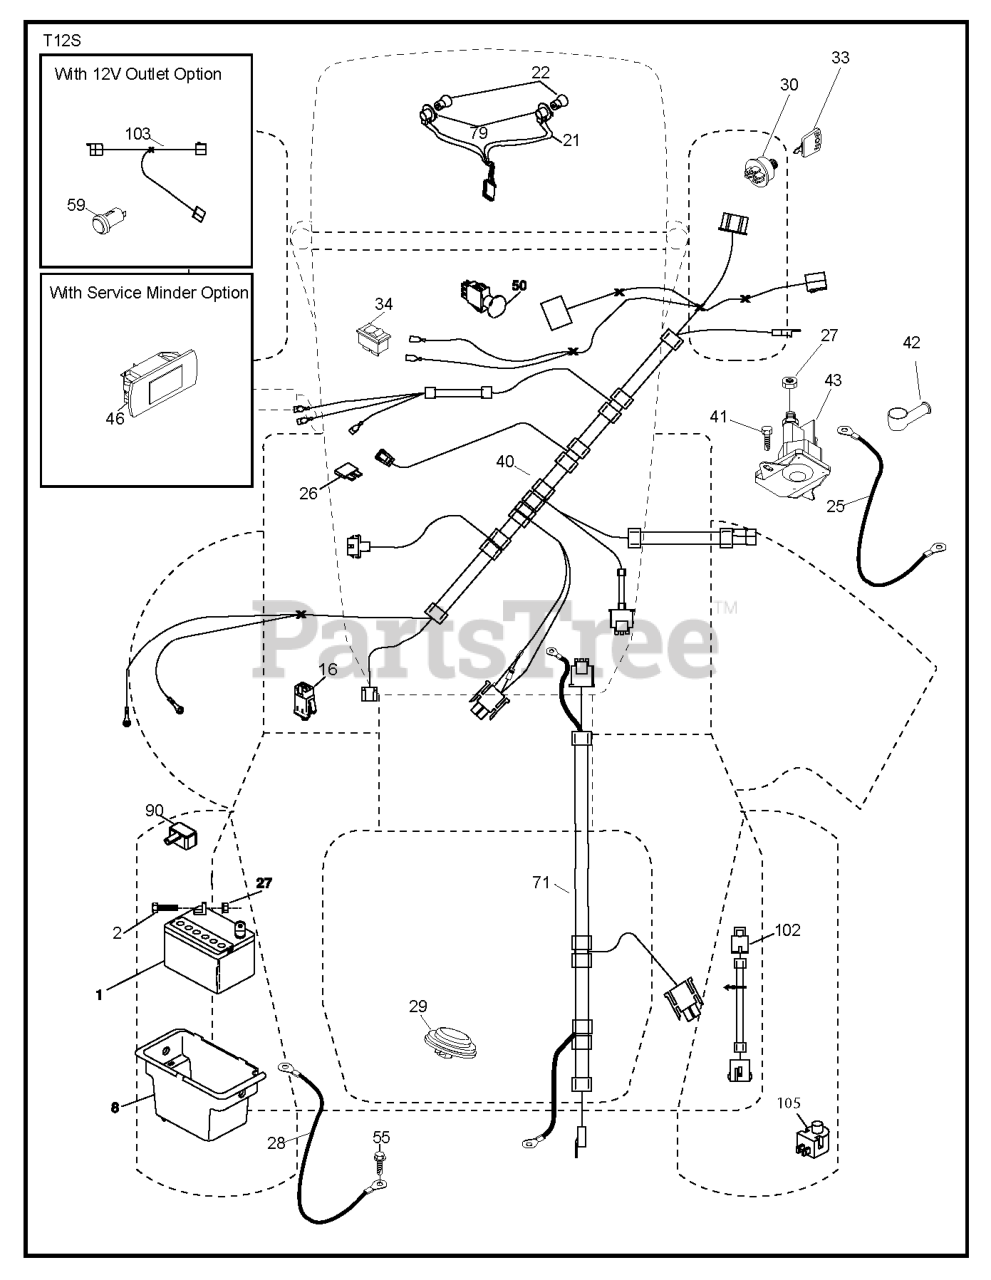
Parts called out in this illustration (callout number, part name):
1	Battery 12 Volt 25 Amp
2	BOLT.HEX.1/4.X.3/4.DICHROMATE
8	BOX.BATTERY.MNT.REAR.L
16	SWITCH INTERLOOK PUSH-IN
21	HARNESS.LIGHT W/4152J BULBS
25	CABLE.STARTER.6GA.BL/RED.14.
26	FUSE 20AMP
27	NUT
28	CABLE.BLACK.18"REAR.BA
29	SWITCH.SEAT.DELTA.OPC.
30	SWITCH.IGN.DELTA.W.LGH.ROS
33	KEY.CHAIN.BLISTER.PACK.GEN.USA
40	HARNESS.IGN.DASH.HUQ/P
41	SCREW
42	TERMINAL COVER
43	SOLENOID.W/BRASS.PLUNGER
46	RP.GUAGE.SRVCMNDR.HRMTR.
50	RP.PTO.SWITCH.8 TERMINAL.BLACK
55	SCREW 5/16"
71	HARNESS.IGN.CHASS.TEX.REAR.BAT
79	BULB HOLDER ASM.
90	COVER, TERMINAL BATTERY
102	HARNESS PIGTAIL PCH TEX ROS
105	REVERSE SWITCH
